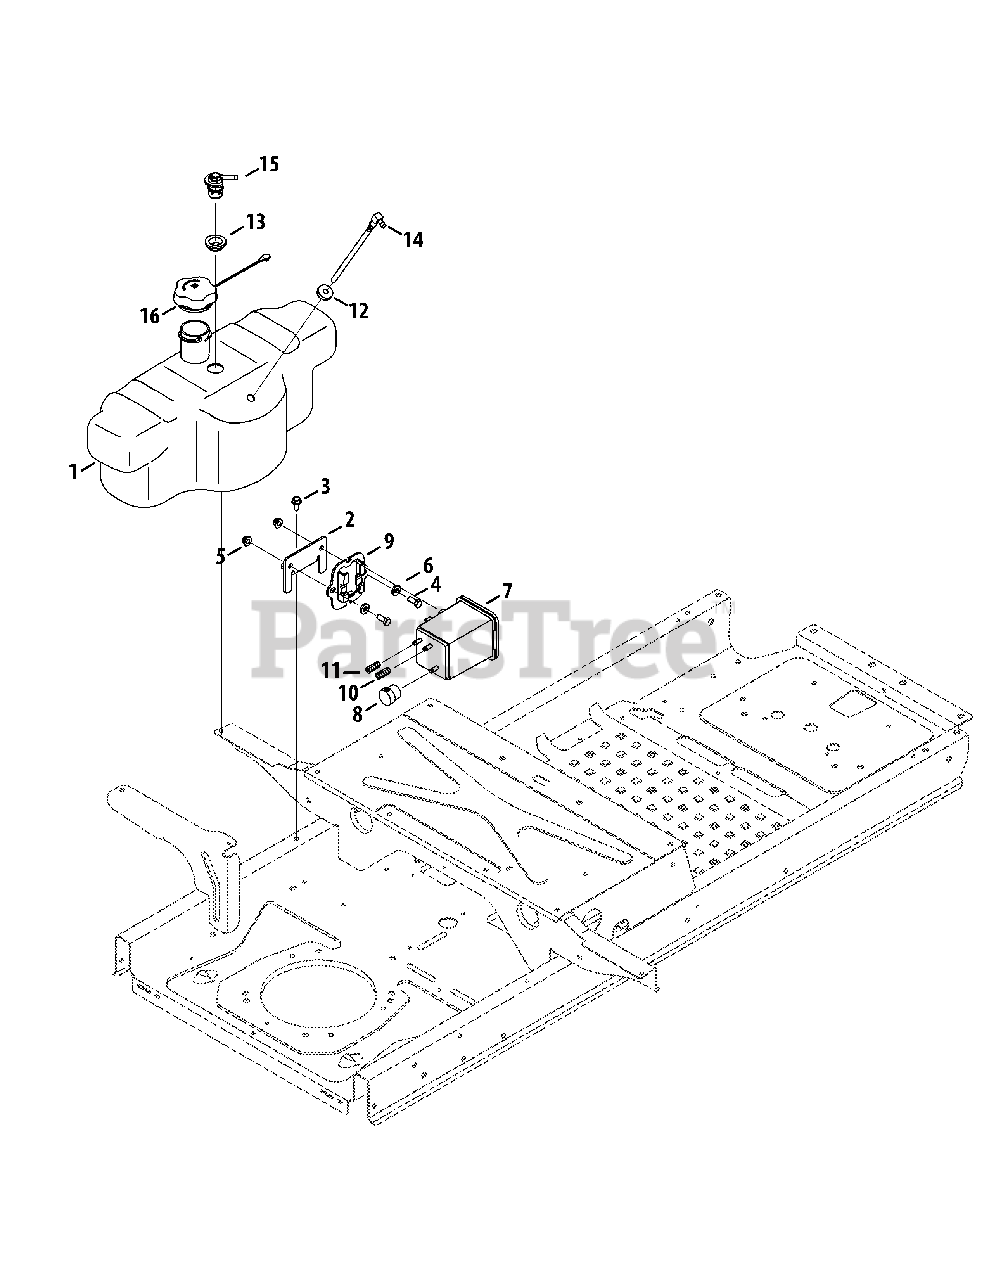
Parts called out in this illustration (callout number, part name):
1	Fuel Tank
2	Carbon Canister Bracket
3	Hex Washer Screw, 5/16-18 x .750
4	Hex Screw, 5/16-18 x .75
5	Flange Lock Nut, 5/16-18
6	Flat Washer, .344 x .750 x .120
7	Carbon Canister
8	Cannister Filter Vent
9	Cannister Adapter Bracket
10	Low Perm Fuel Hose 7/32 Yellow
11	Vent Hose, Carb
12	Fuel Tank Bushing
13	Rubber Grommet
14	Fuel Pickup Fitting
15	Rollover Valve
16	Fuel Cap
